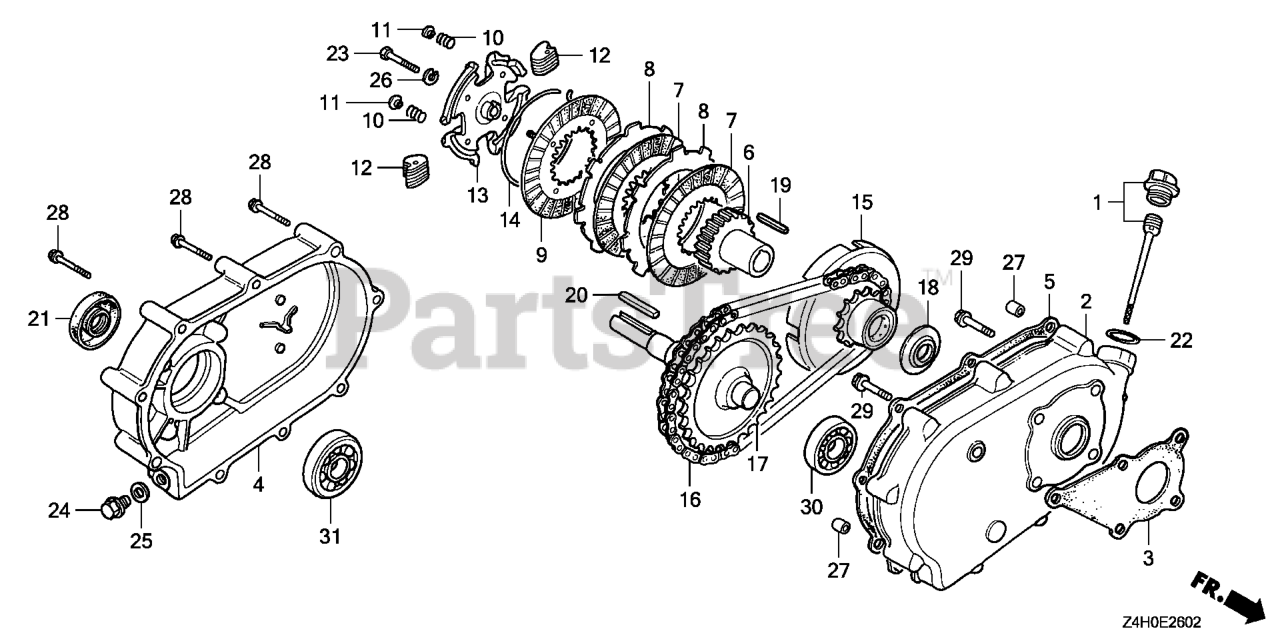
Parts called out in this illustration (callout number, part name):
1	CAP ASSY., OIL FILLER
2	CASE, REDUCTION
3	GASKET, REDUCTION CASE
4	COVER, REDUCTION
5	GASKET, REDUCTION COVER
6	CENTER, CLUTCH (28T)
7	DISK, CLUTCH FRICTION
8	PLATE, CLUTCH
9	PLATE, CLUTCH PRESSURE
10	SPRING, CLUTCH FREE
11	HOLDER, CLUTCH SPRING
12	WEIGHT, CLUTCH
13	HOLDER, CLUTCH WEIGHT
14	CENTER, CLUTCH WEIGHT
15	SPROCKET, DRIVE
15	SPROCKET COMP,DRI
16	CHAIN, DRIVE (RK428SH-36LE)
17	SHAFT, P.T.O. (28T)
18	WASHER, THRUST (18MM)
19	KEY (5MM)
20	KEY (7X7X33)
21	OIL SEAL (30X50X7)
22	O-RING (26X2.7)
23	BOLT, HEX. (8X35)
24	BOLT, DRAIN PLUG (12MM)
25	WASHER, DRAIN PLUG (12MM)
26	WASHER, SPRING (8MM)
27	PIN A, DOWEL (8X10)
28	BOLT, FLANGE (6X55)
29	BOLT, FLANGE (8X22) Use from Engine SN 1609607.
30	BEARING, RADIAL BALL (6205)
31	BEARING, RADIAL BALL (6206)
